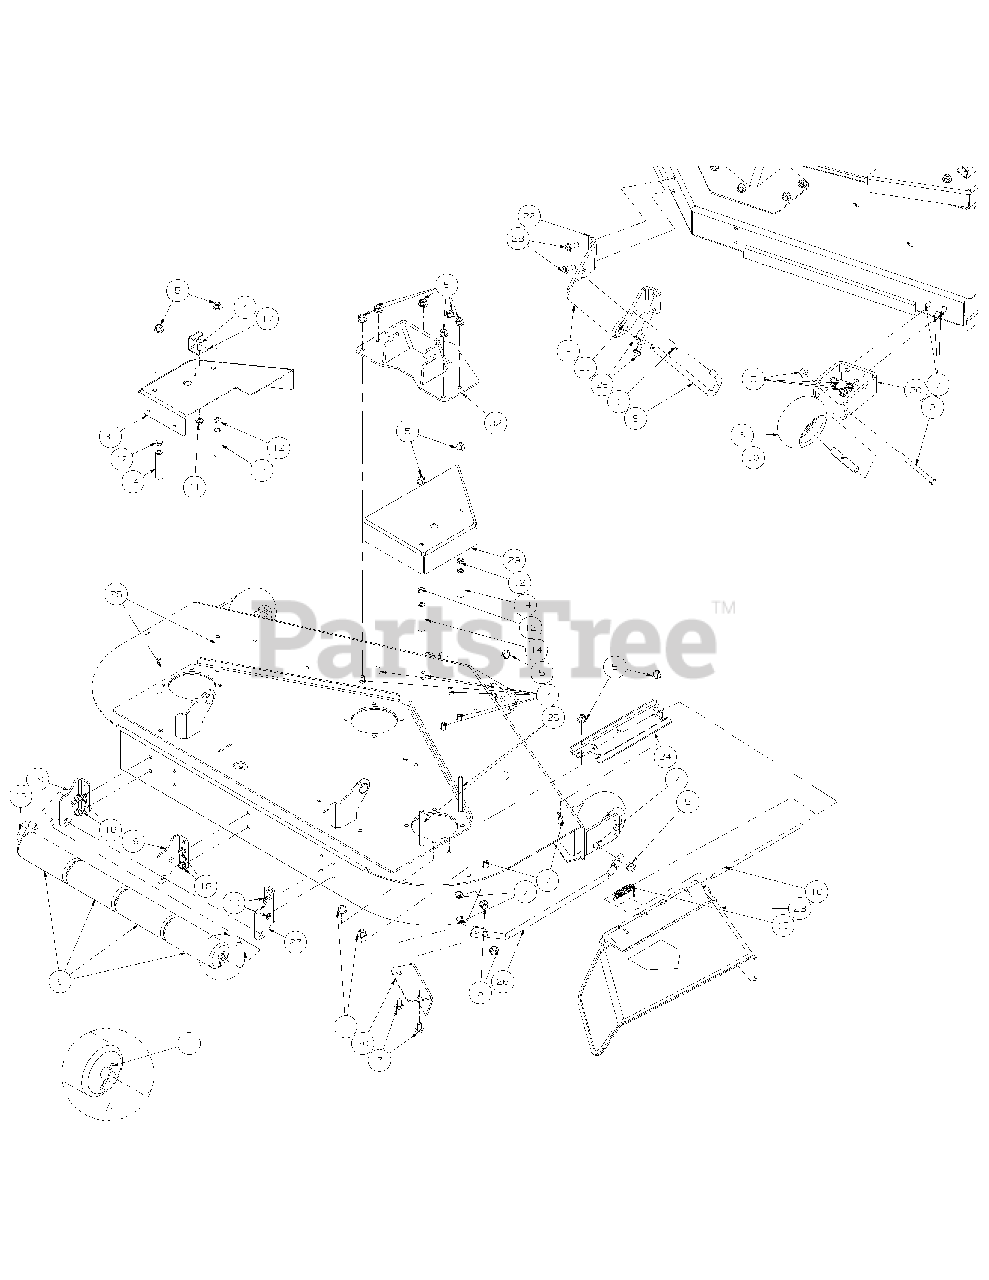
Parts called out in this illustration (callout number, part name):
1	Cotter Pin, .125 Dia. x 1.0
2	Carriage Bolt, 3/8-16 x 1.25
3	Hex Cap Screw, 3/8-16, 3.75
4	Hex Head Cap Screw, 5/16-18 x .75
5	Hex Nut, 3/8-16 Flange Lock
6	Complete Wheel, 5.00 Dia
7	Carriage Bolt 3/8-16 x .75
8	Roller Pin 1/2 x 7.31
9	Front Roller
10	Wheel Spacer
11	Hex Nut, 5/16-18 Flange Lock
12	Nut, 3/8-16, Jam
13	Roller Pin
14	Spacer, .39 ID x .625 OD x 2.75
15	Torsion Spring
16	Chute Deflector Rod
17	Stop Bracket
18	Self Tapping Screw, 5/16-18 x 1/2
19	Fabricted Deck Roller Mount Bracket
20	Front Anti-Scalp Wheel Mount Bracket
21	Left Hand Front Roller Mount Bracket
22	Right Hand Front Roller Mount Bracket
23	Deflector Chute
24	Deflector Chute Bracket
25	Carriage Bolt, 3/8-16 x 4.00
26	Fabricated Deck Finger Guard
27	Grass Catcher Roller Bracket
28	Self Tapping Screw, 3/8-16 x 0.875
29	Belt Cover, RH
30	Fabricated Deck, Chute Bracket
31	Belt Cover, LH
32	Front Lift Bracket Weldment
